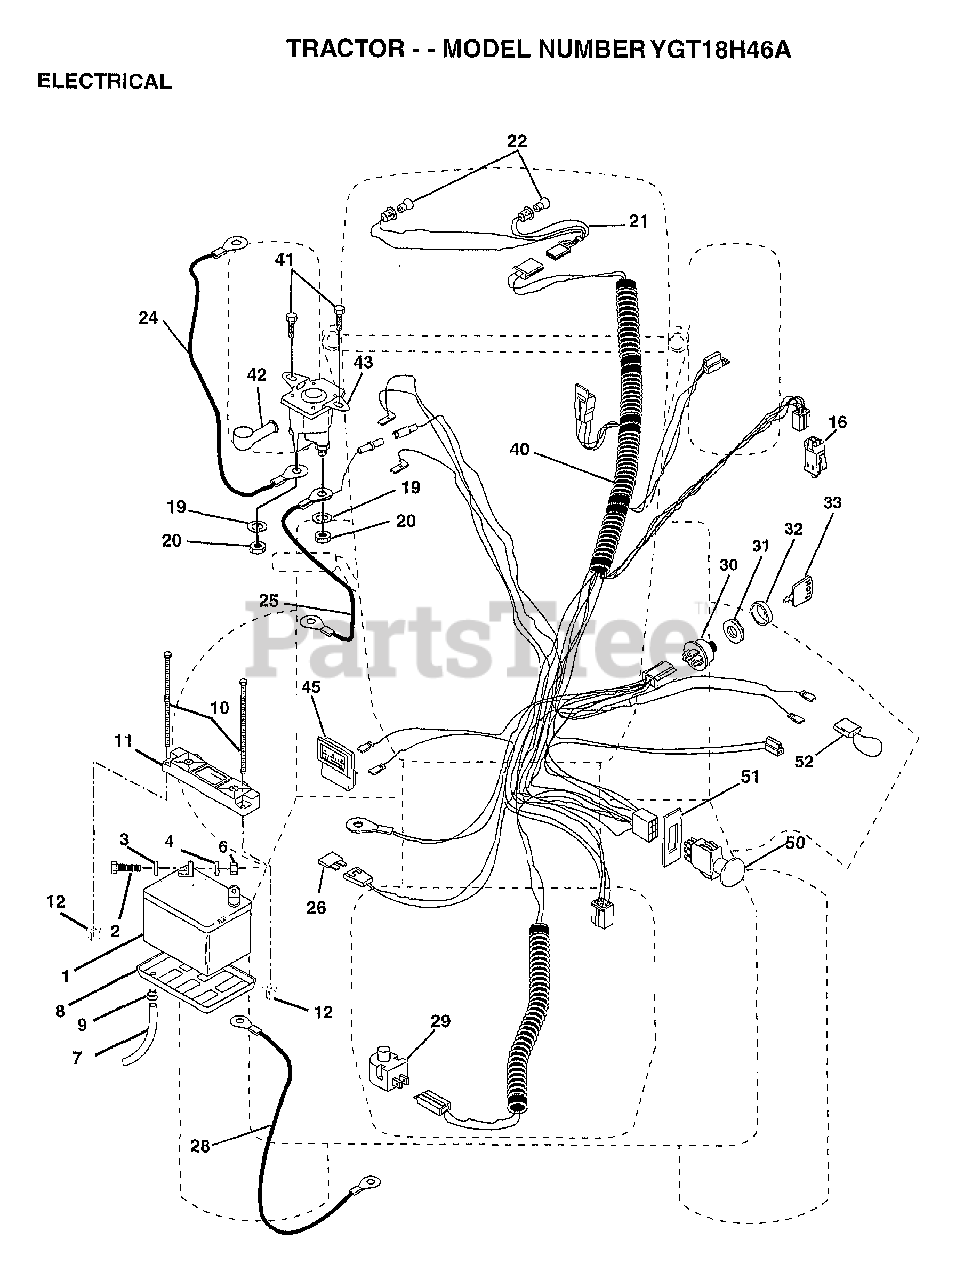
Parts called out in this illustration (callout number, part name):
2	BOLT LT
3	LOCKWASHER
4	WASHER
7	"DRAIN TU T, BATT"
8	"TRAY T, BATTERY"
9	HOSE CLAMP T
11	HOLDDOWN BATTERY
16	SWITCH INTERLOCK
20	NUT
21	"HARNESS,LIGHT SOC"
22	HEADLAMP BULB
24	CABLE.BATY.22.RED
25	CABLE.BATRY.4GA.
26	FUSE HYT
28	"CABLE BATTERY,GRD"
29	SWITCH SEAT
30	BEARING PVT LH
31	NUT IGNITION
32	COVER KEY SWITCH
33	KEY
40	HARNESS IGNITION
41	SCREW
45	AMMETER
50	PTO SWITCH.BLK
51	RING RETAIN PTO
52	PROTECTION LOOP
